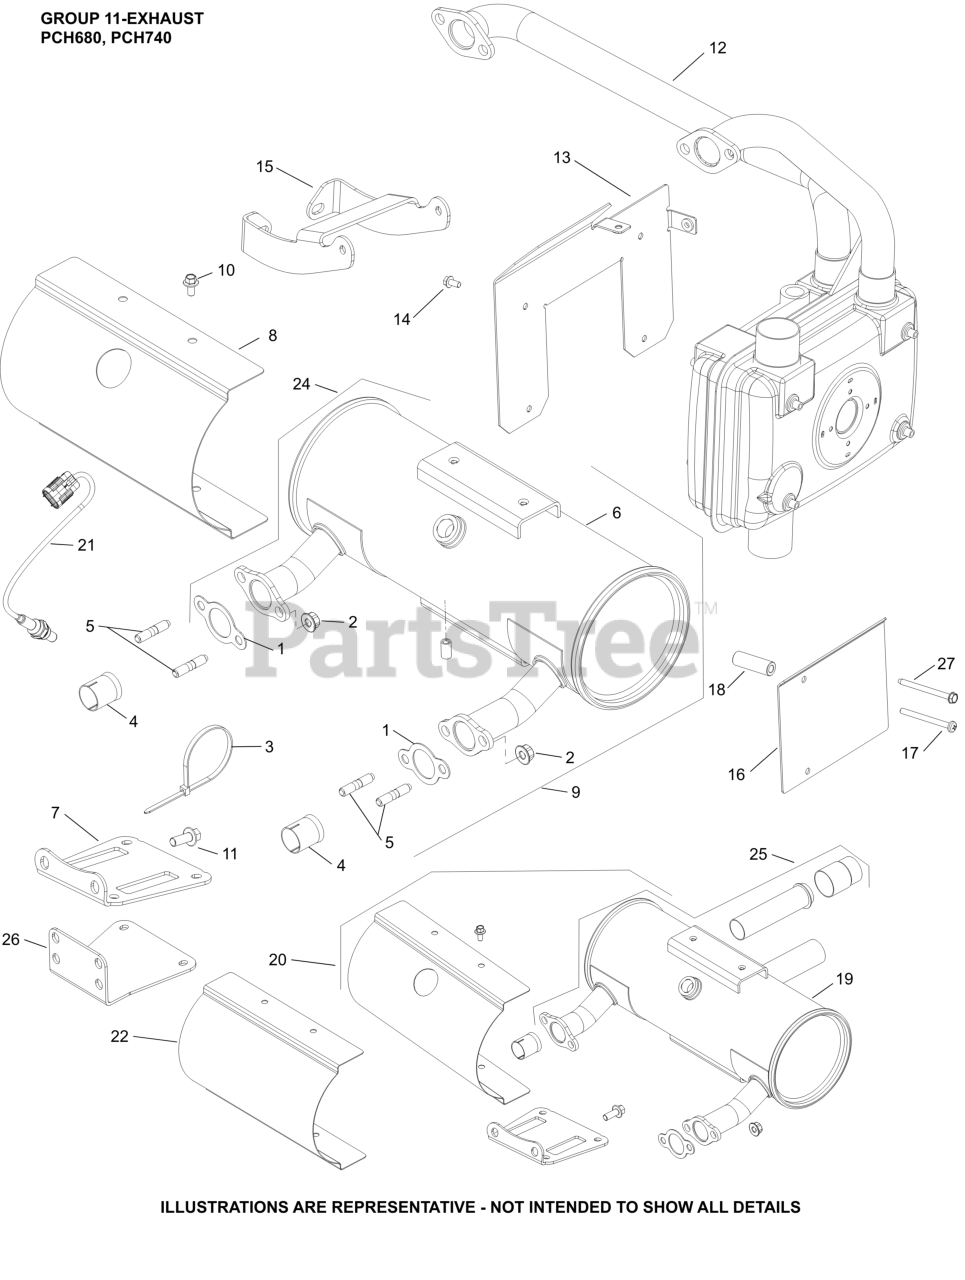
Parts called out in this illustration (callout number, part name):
1	GASKET, EXHAUST
2	NUT, HEX FLANGE LOCK (M8)
4	LINER, EXHAUST PORT
5	STUD, METRIC EXHAUST
21	SENSOR, OXYGEN (M18 x 1.5 THREADS)
